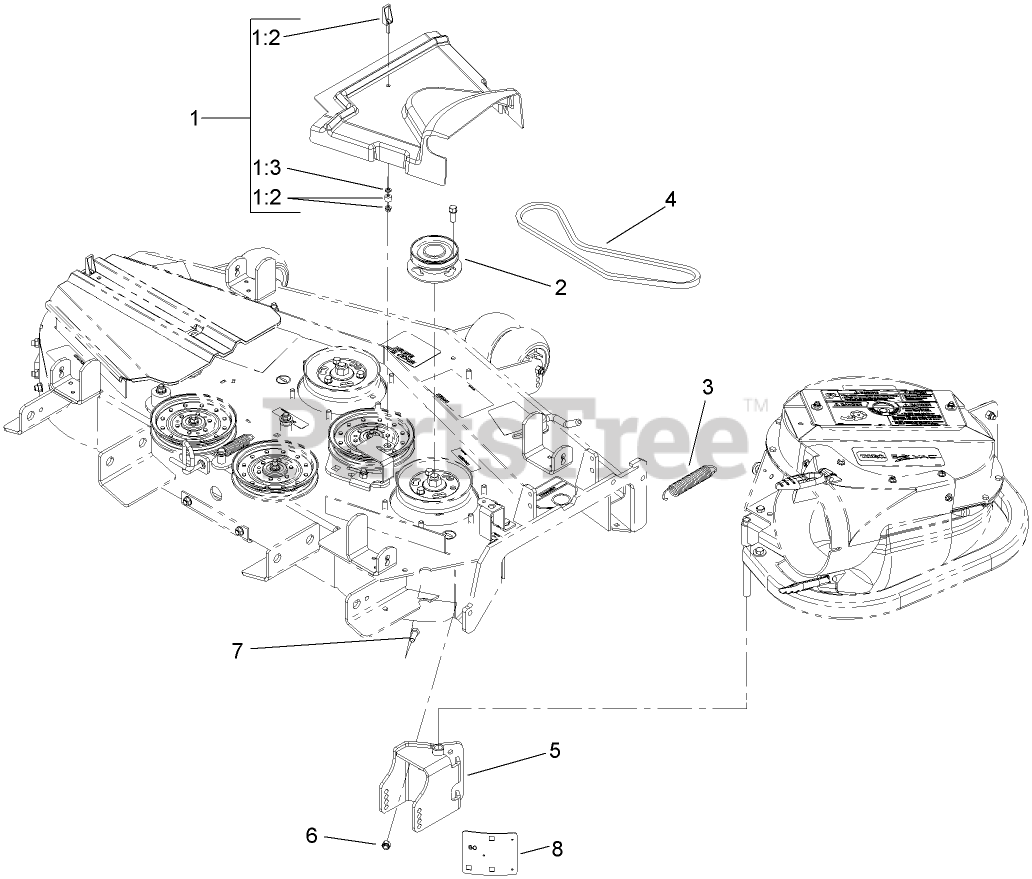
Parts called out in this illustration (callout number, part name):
1	BELT COVER ASM
1:2	LATCH-SWELL
1:3	WASHER
2	PULLEY ASM
3	SPRING-EXTENSION
4	BELT-V
5	HINGE-BLOWER
6	NUT-LOCK, NI
7	SCREW-HH
8	TEMPLATE
